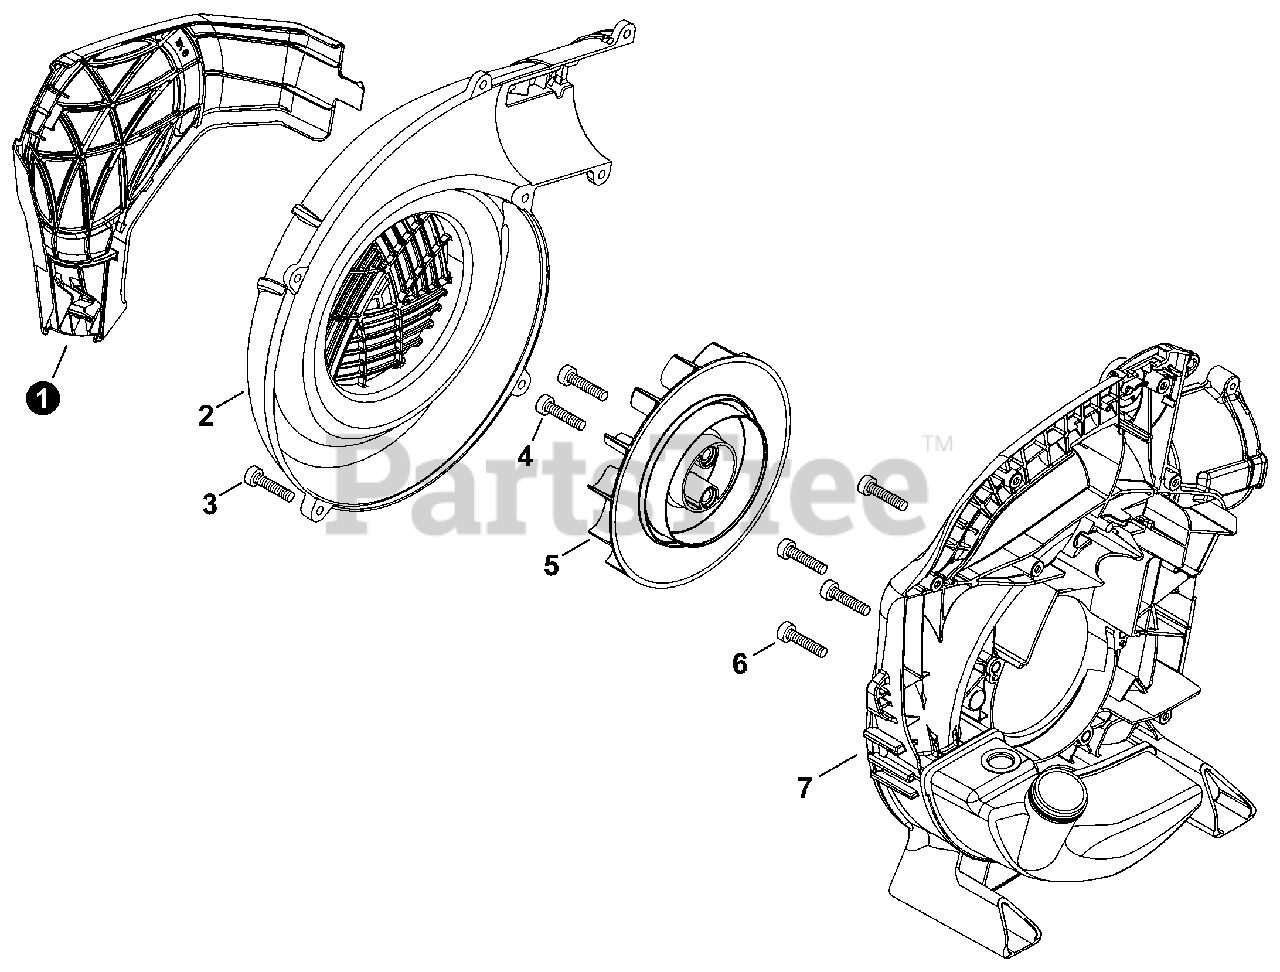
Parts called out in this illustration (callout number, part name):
1	GUARD, LEAF
2	COVER, FAN CASE
3	BOLT, TORX 5×20
4	BOLT, TORX 6×20
5	FAN, BLOWER
6	BOLT, TORX 5×16
7	CASE, FAN
